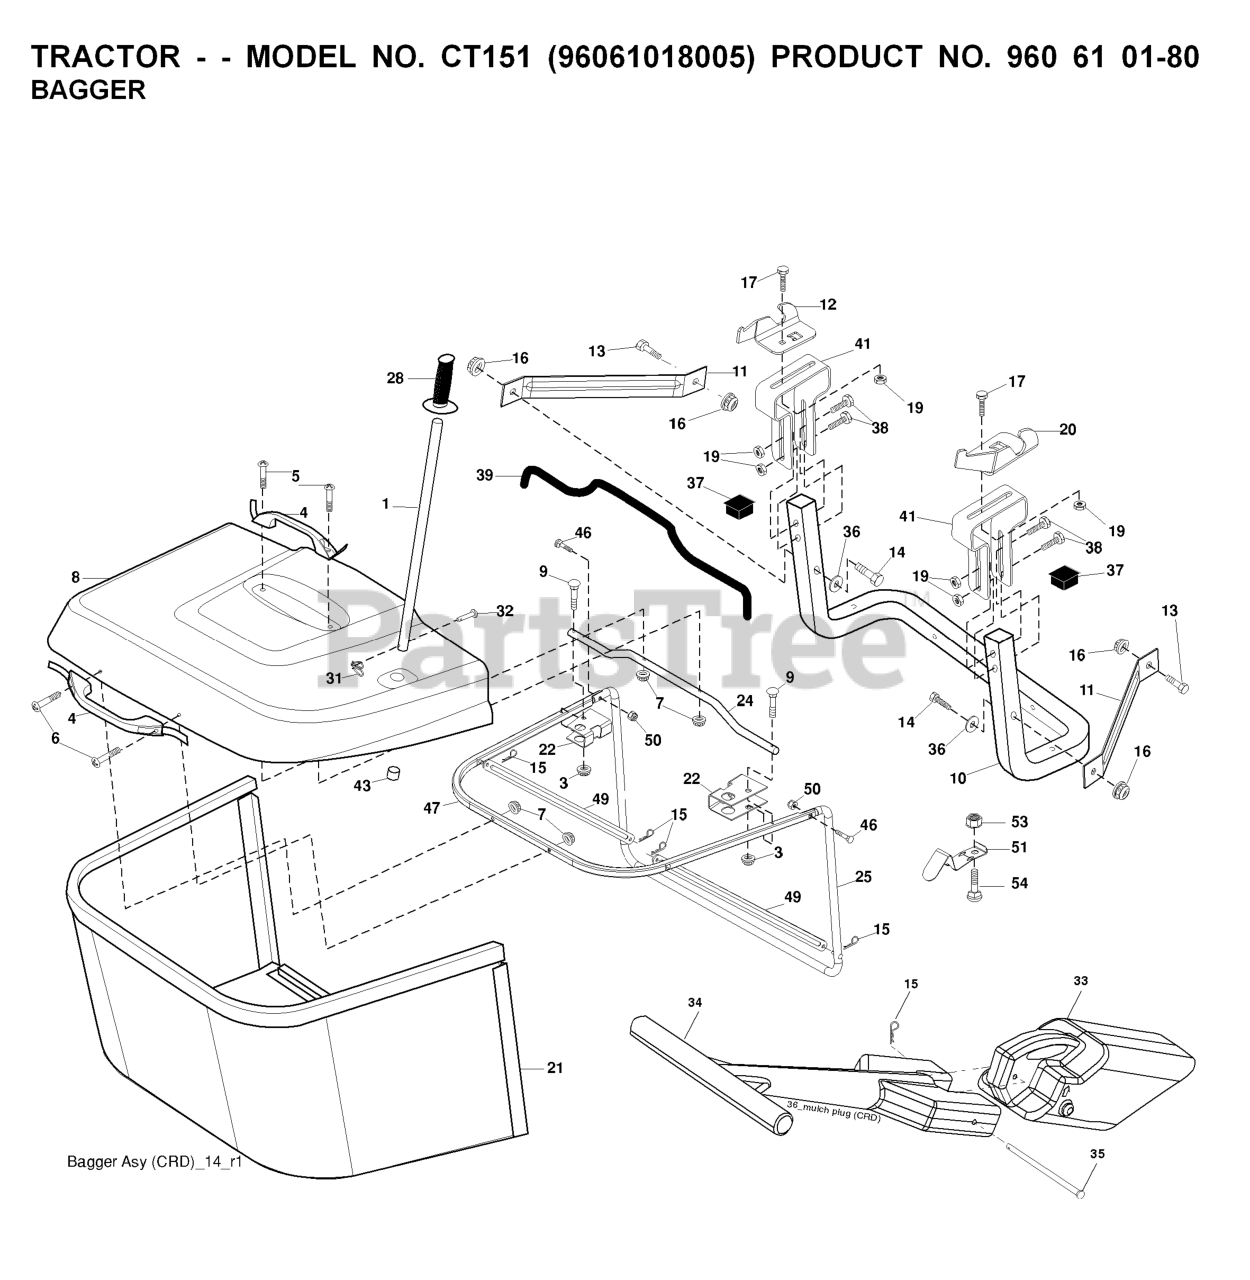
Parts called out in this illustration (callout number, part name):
1	TUBE HANDLE
3	NUT T
4	HANDLE.BAGGER.W/LVRS.BLK.CRD
5	SCREW.PAN.HEAD
6	REPL BY 532 75 00-29
8	COVER.PNT.BGR.CRD.WSLOTS.MS668
9	Bolt Carriage 1/4-20 x 2.25d x Gr.5
10	TUBE
11	BRACKET.SUPPORT.UPPER.BAG.CRD
12	BRKT PIVOT
14	BOLT-HEX EAK
15	RETAINER-SPRNG RB
16	NUT LOCK FLG 3/8-16 UNC
17	RP BOLT 5/16-18 X3/4 ZN/YEL GR
19	NUT LOCK HEX FLANGE 5/16-18
20	BRKT.PIVOT.RH.CRD
21	BAGGER.ASM.CRD.2007
22	BRKT.SIDE.BAG.CRD
24	TUBE.PIVOT.BAG.CRD.BLACK
25	PIPE
28	GRIP.HANDLE.BLACK
31	RETAINER CLIP
32	RIVET,DRILLED
33	PLUG.MULCHER.92 CRD
34	HANDLE.MULCHER.92.CRD (2 2)
36	WASHER
37	Plug Support Bagger CRD
38	BOLT.5/16-18X2.5
39	SEAL.BAGGER.CRD
41	BRKT.VERT.ADJ.BAGGER.CRD
43	PLUG, TUBING END
46	BOLT.CARRIAGE.5/16-18
47	PIPE
49	ROD
50	NUT.71038.31-18.HEX.NYLOCK
51	LATCH
53	NUT
54	BOLT
